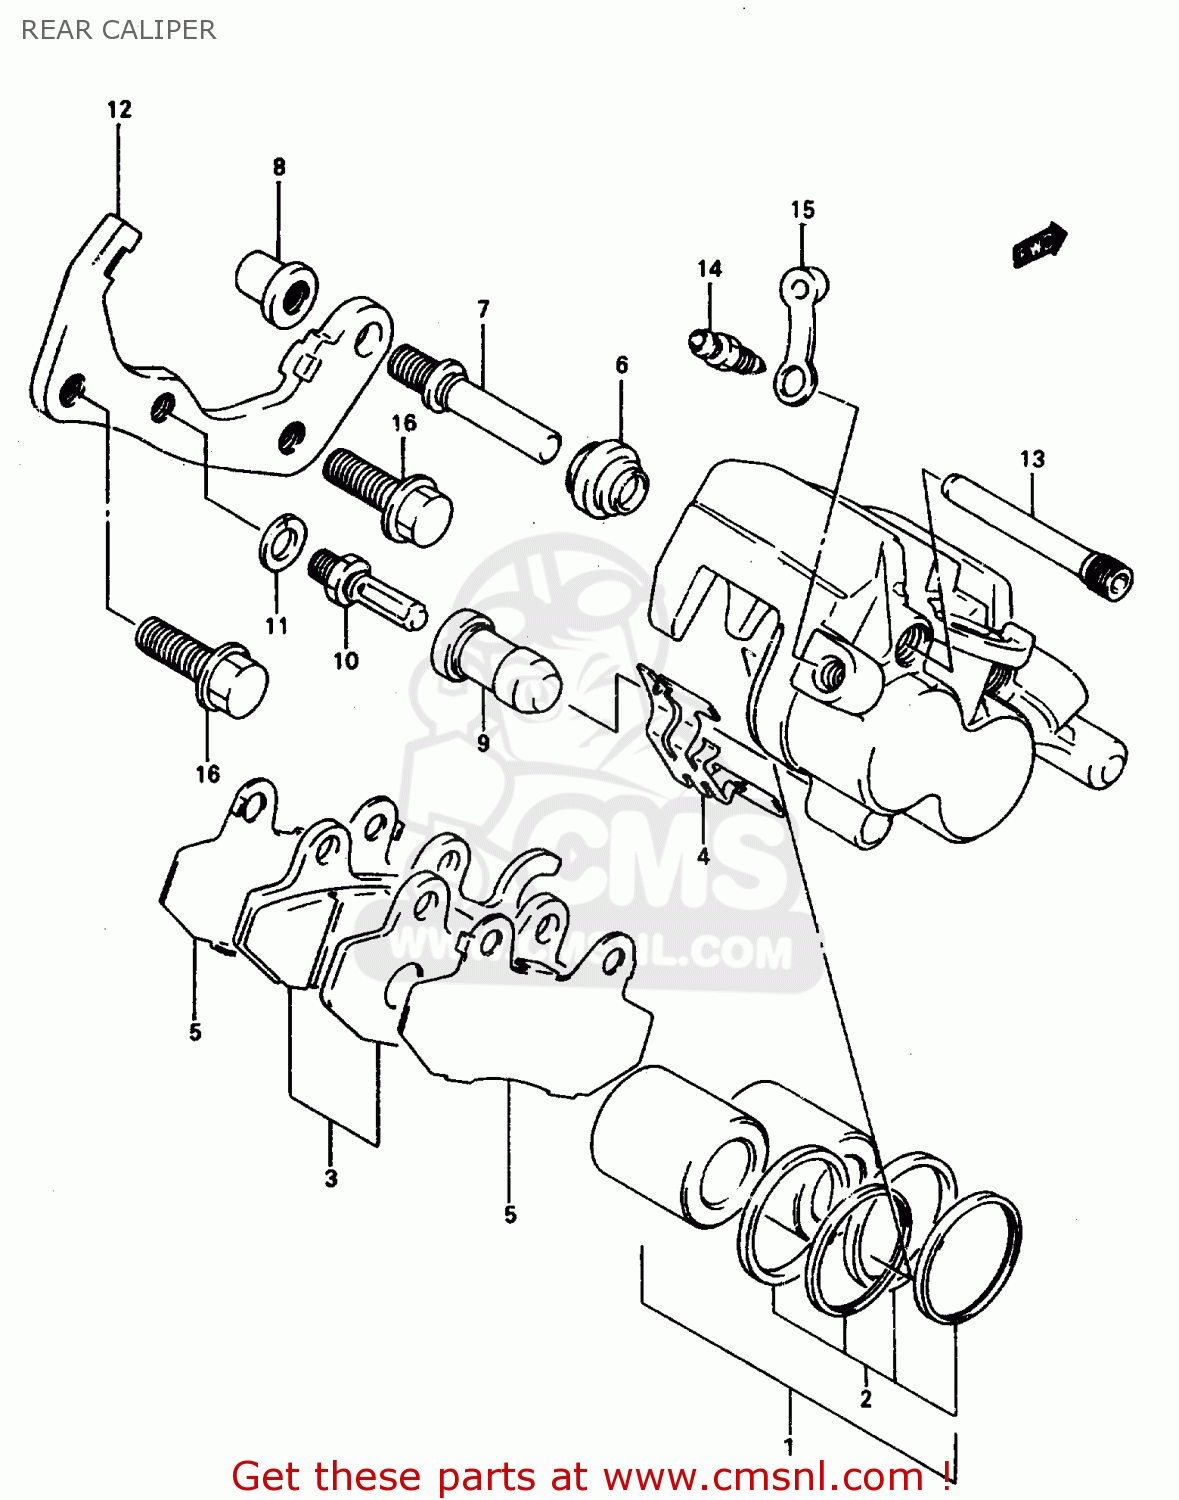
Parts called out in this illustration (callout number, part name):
1	PISTON SET
2	SEAL SET,PISTON
3	PAD SET (NAS)
4	SPRING,PAD
5	SHIM
6	BOOT
7	PIN,SLIDE
8	NUT
9	BOOT
10	BOLT,PIN
11	WASHER,WAVE
12	BRACKET
13	PIN,HANGER
14	BLEEDER
15	CAP,BLEEDER
16	BOLT(10X23)
